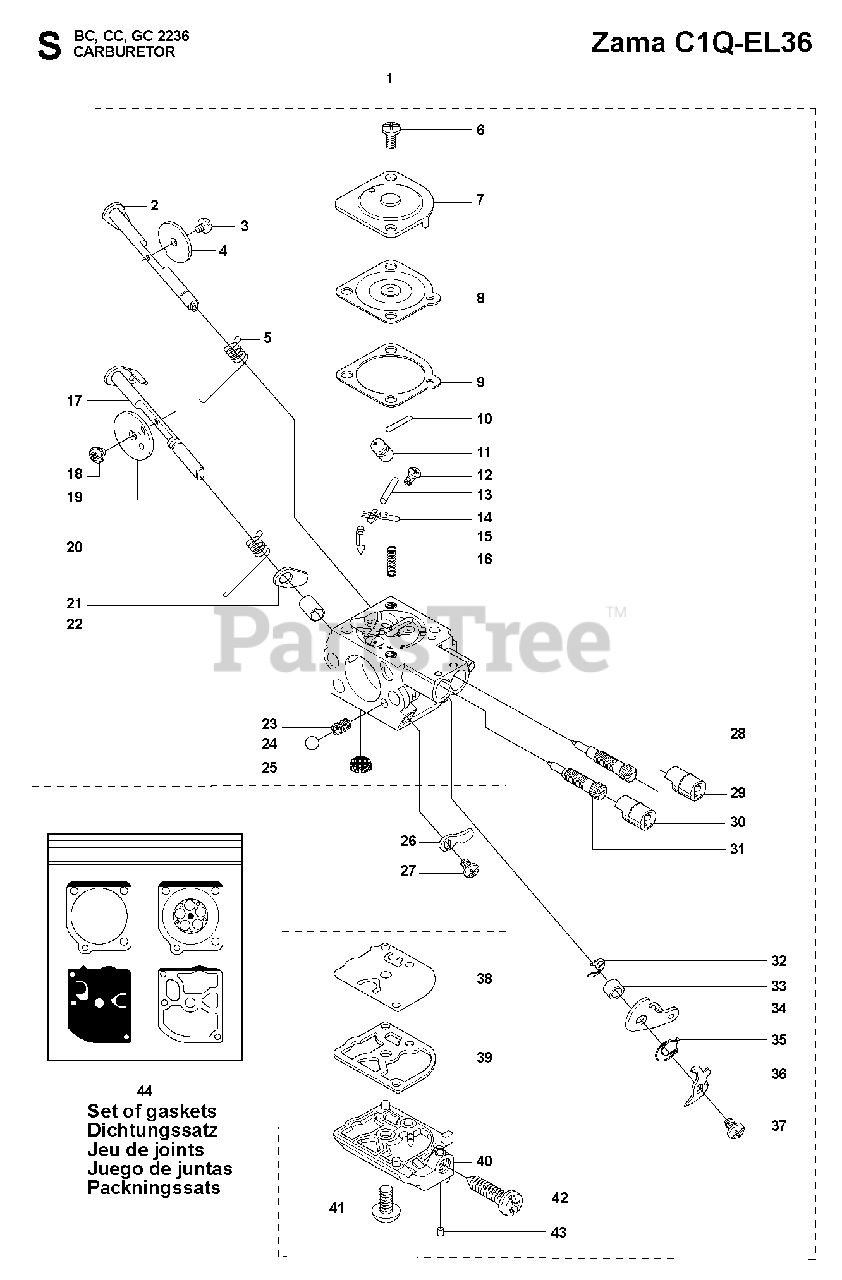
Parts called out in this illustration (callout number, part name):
1	CARBURETOR C1QEL36
2	THROTTLE SHAFT
5	RETURN SPRING
8	DIAPHRAGM
9	GASKET
13	PIN FULCRUM
15	INLET NEEDLE
16	SPRING
17	CHOKE SHAFT
19	DISC
25	FUEL INLET SCREEN
28	IDLE SCREW
29	LIMITER CAP KIT
30	LIMITER CAP KIT
31	SCREW
38	PUMP DIAPHRAGM
39	GASKET
44	GASKET KIT (ZAMA GND39)
